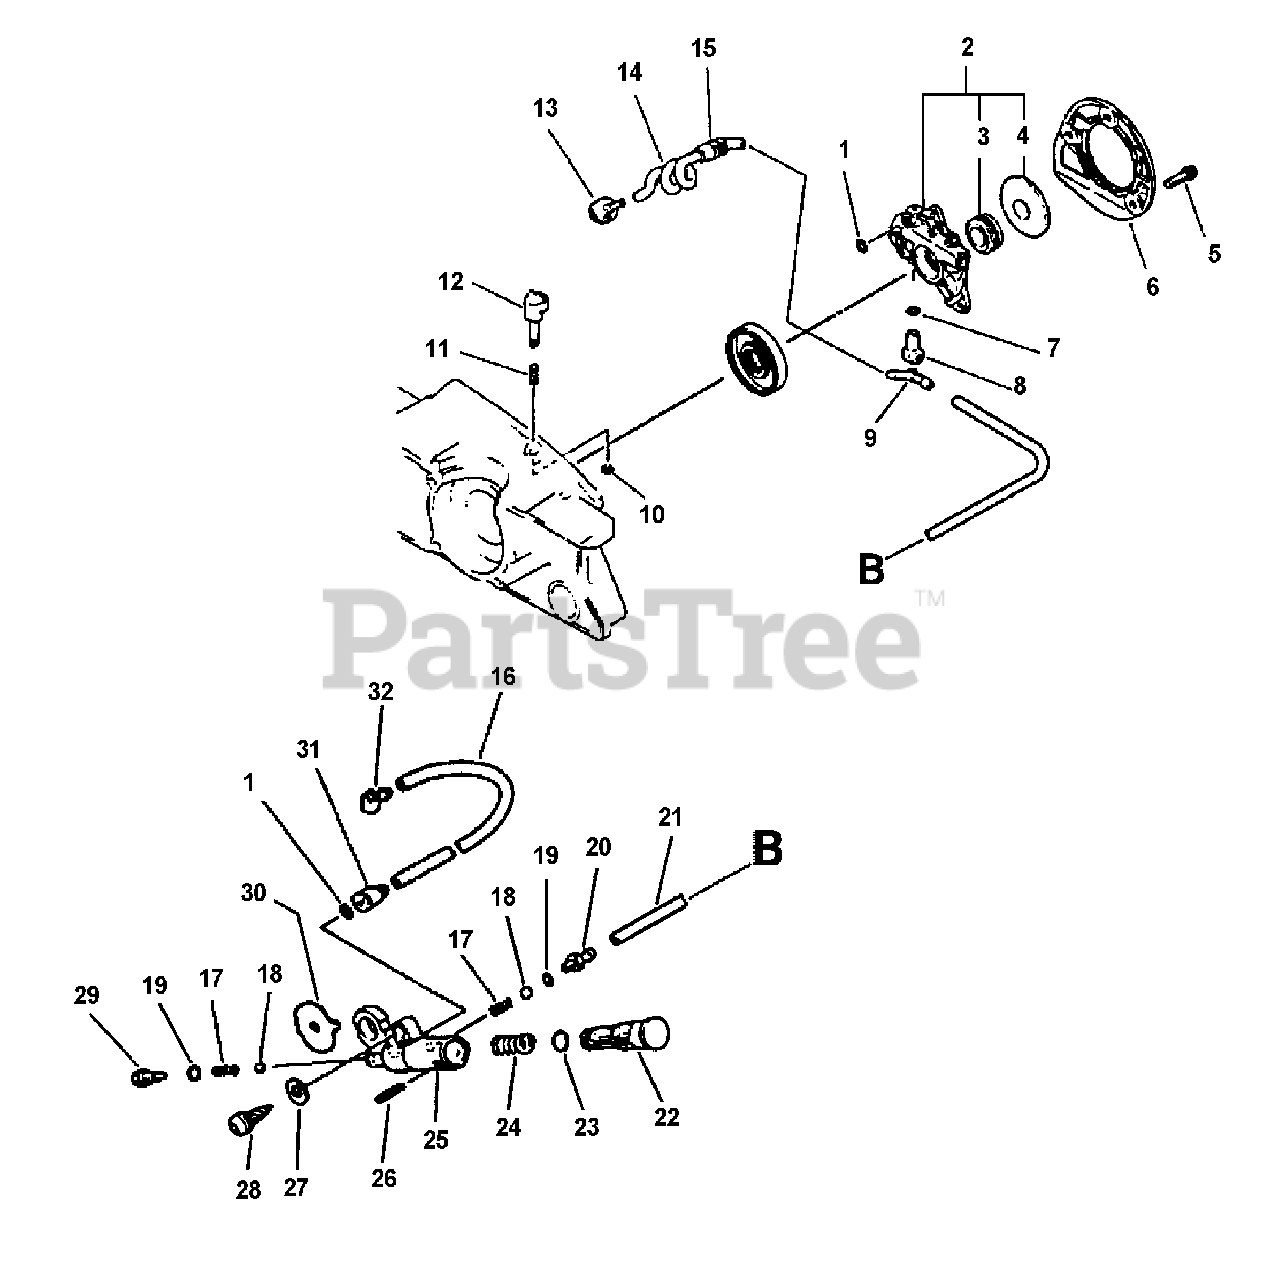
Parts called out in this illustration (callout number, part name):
1	O-RING 3
2	AUTO-OILER ASSY
3	GEAR, WORM
5	BOLT 4×12
6	COVER, OIL PUMP - GRAY
7	CLIP Ø6.5 MM
8	CONNECTOR, PIPE
9	PIPE, OIL 3×6×20
10	E-RING 3
13	FILTER, OIL
14	PIPE, OIL
15	OIL PUMP ASSY
16	PIPE 3×6×125 BLACK
17	SPRING, VALVE
18	VALVE, BALL
20	CONNECTOR, PIPE
21	PIPE, OIL
22	PISTON, OIL PUMP - ORANGE
23	O-RING 7 MM
25	BODY, OIL PUMP
26	PIN, SPRING 2×16
27	WASHER 5.5×12×0.8
28	SCREW 5×20
29	ADAPTOR, OIL PUMP
30	BRACKET, OIL PUMP
31	CONNECTOR, PIPE
32	CONNECTOR, PIPE
